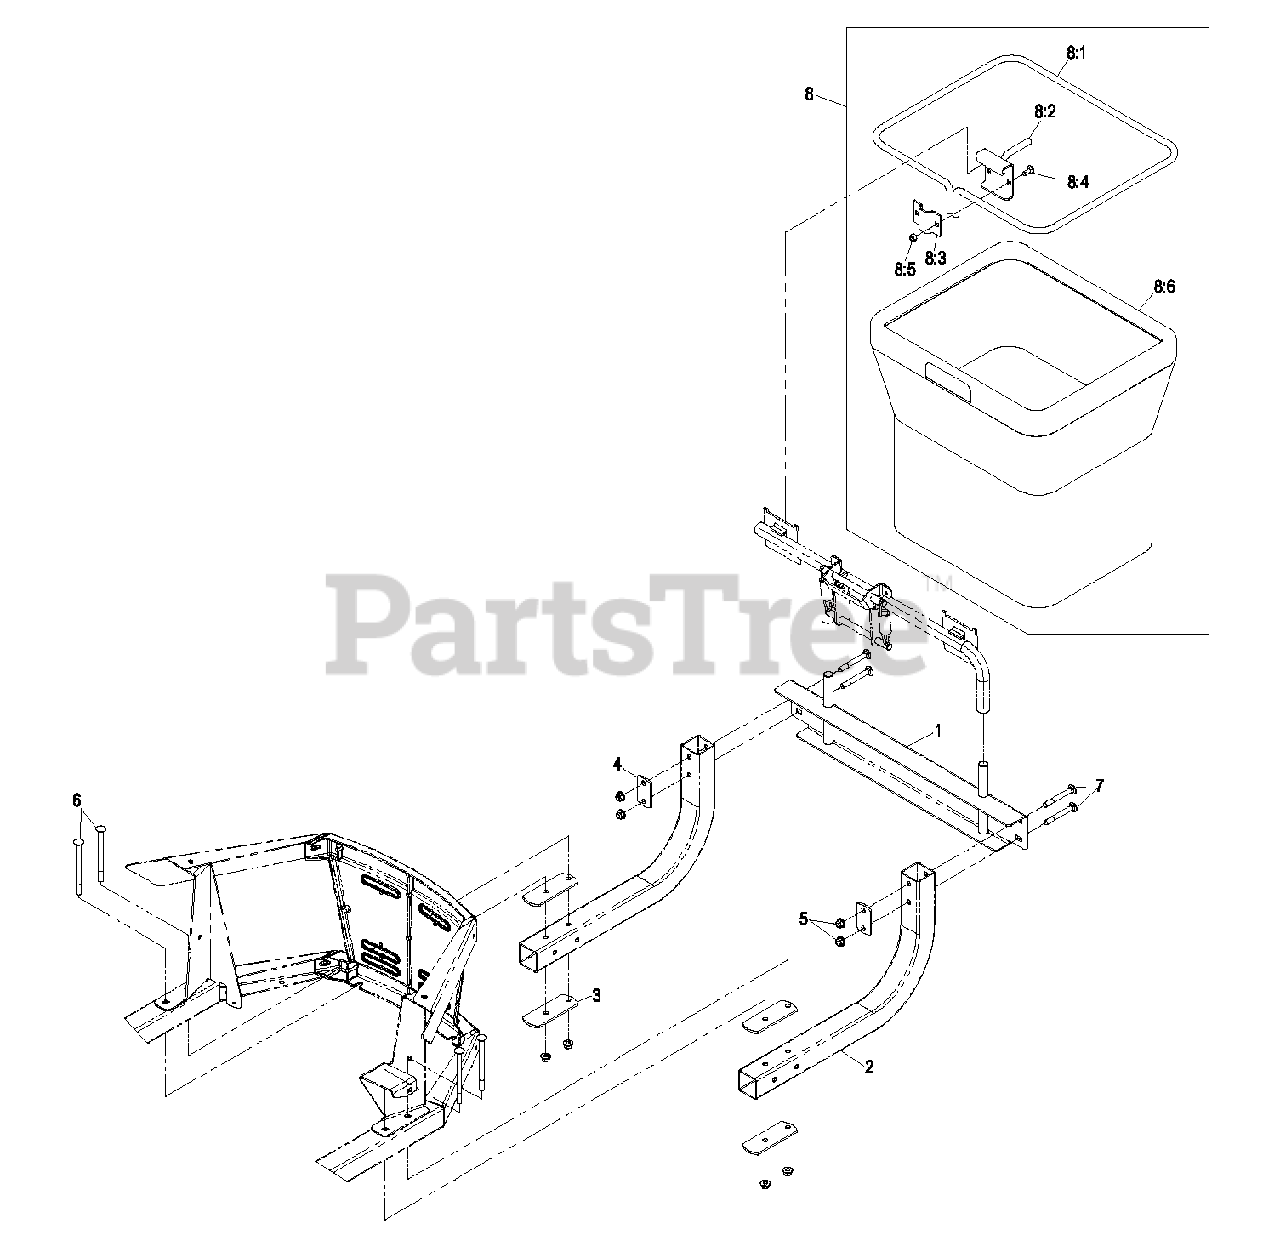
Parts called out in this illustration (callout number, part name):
1	BAGGER HITCH ASM
2	TUBE-HITCH, BAGGER
3	PLATE-STIFFENER
4	PLATE-STIFFENER
5	NUT-HF, NI
6	BOLT-CARR
7	SCREW-CARR
8	BAG ASM
8:1	FRAME-BAG
8:4	BOLT-CARR
8:5	NUT-LOCK, NI
